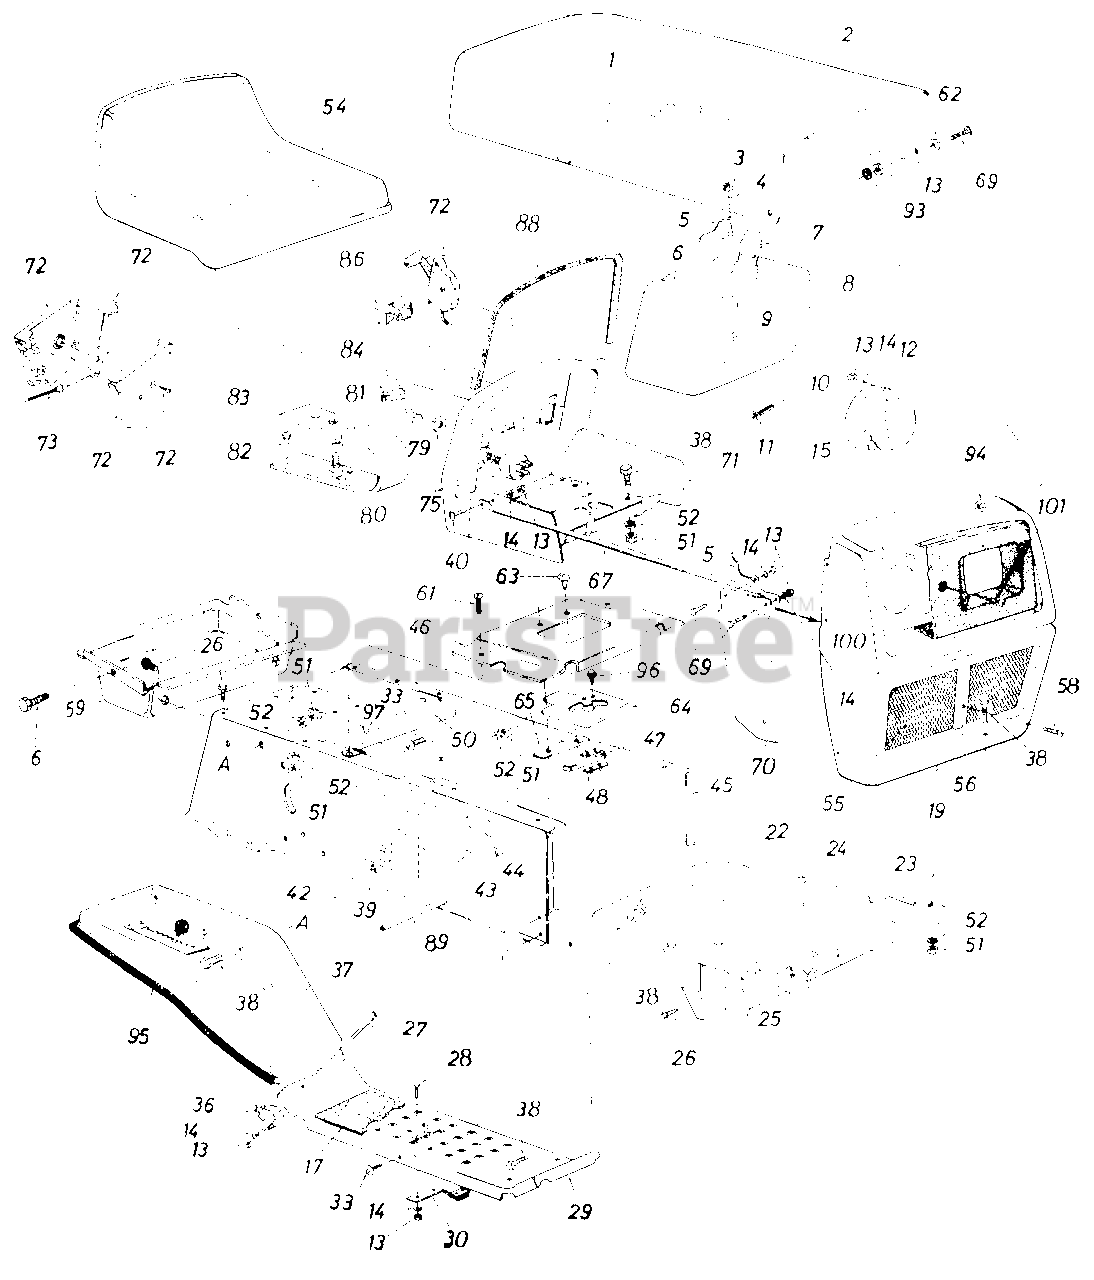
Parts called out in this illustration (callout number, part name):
1	Hood Spring
2	Hood
3	Hex Sems Nut #10-24 Thd.*
4	Fl-Wash. .281" I.D. x .62" O.D. x .051
5	Hood Stop 7" Lg.
6	Truss Hd. Scr. #10-24 x 1/2"*
7	Fuel Cap Gauge
8	Fuel Tank
9	Tie Strap
10	Fuel Line
11	Hose Clamp
12	Headlight Retainer
13	Hex Nut 1/4-20 Thd.*
14	L-Wash. 1/4" I.D.*
15	Headlight
17	Foot Pad
19	Grille Ass'y.
22	Lower Frame
23	Grille Mount Brkt. L.H.
24	Front Pivot Brkt.
25	Grille Mount Brkt. R.H.
26	Hex Wash. Hd. AB-Tap Scr. 5/16 x .75" Lg.
27	Truss Hd. Scr. 1/4-20 x 1.75" Lg.*
28	Carriage Bolt 1/4-20 x .62" Lg.*
29	Running Board
30	Blade Brake Ass'y.
33	Truss Mach. Scr. 5/16-18 x .75" Lg.*
36	Fender Clamp
37	Fender (R.H.)
39	R.H. Side Frame
40	Hex Bolt 1/4-20 x .62" Lg.*
42	Battery Strap Hook
43	Battery Hold Down Strap
44	12-V Battery
45	L.H. Side Frame
46	Shift Cover
47	Reverse Safety Switch
48	Insulator Nut Plate
50	Hitch Plate
51	Hex Nut 5/16-18 Thd.*
52	L-Wash. 5/16" I.D.*
54	Seat Ass'y.
55	Grille Screen
56	Moulding
58	Hex Wash. Hd. F-Tap Scr. #8-32 x .38" Lg.
59	Tool Tray
62	Fl-Wash. .296 I.D. x .62 O.D.
63	Truss Mach. Scr. 1/4-20 x .75" Lg.
64	Gear Selection Plate
65	Clamping Plate
67	Grille Support Rod
69	Truss Hd. Scr. 1/4-20 x .75" Lg.*
70	R.H. Grille Side Panel
70	L.H. Grille Side Panel
71	Dash Panel Ass'y.
72	Throttle Control Box Ass'y.
73	Throttle Control Wire
75	Ignition Switch
79	Ignition Key
80	Hex Bolt 1/2-13 x 1.00" Lg
81	L-Wash. 1/2" I.D.*
82	Hex Bolt 5/16-18 x 1.00" Lg.*
83	Seat Spring 5.5" High
84	Light Switch
86	Ammeter
88	Molding Strip 27" Lg.
89	Running Board Rod
89	Thread Rolling Scr. 1/4-20 x .50" Lg.
93	RubberWash. 1/2" I.D. x 1.0 O.D. x .25"
94	Hex Sems Ins. L-Nut 1/4-20 Thd.
95	Trim Strip
96	Hex Wash. Hd. AB-Tap Scr. #8 x .50" Lg.
97	Speed Nut #10Z
100	Bezel
101	Truss Scr. #10-24 x .62" Lg.
